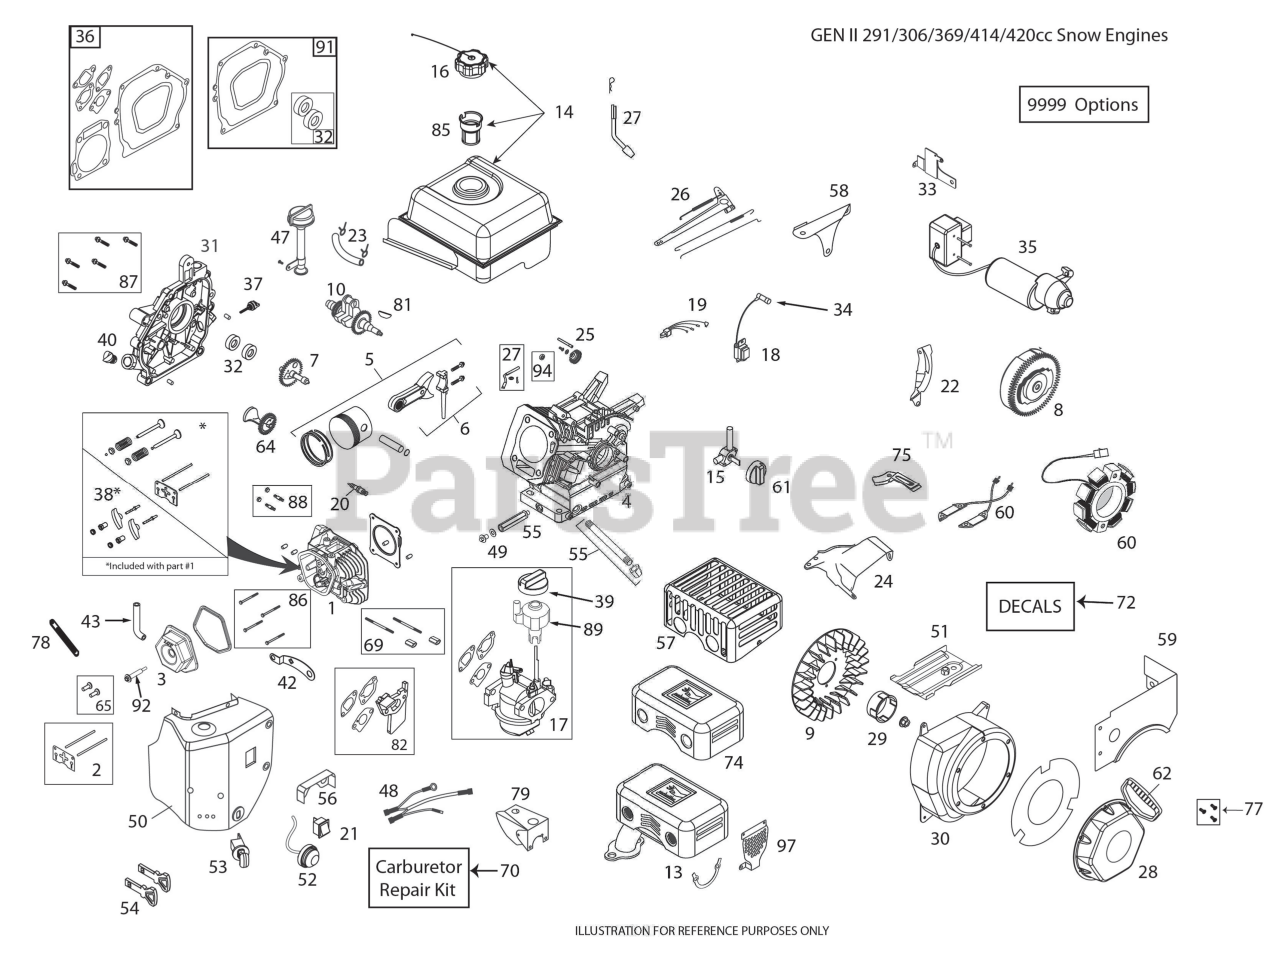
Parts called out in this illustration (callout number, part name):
1	CYLINDER.HEAD.ASSY(SK2911000)
2	PUSH ROD TAPPET KIT
3	VALVE.COVER.LCT.414CC.
4	CYLINDER ASSY SNO.LCT
5	PISTON.AND.ROD.ASSY(SK2911400)
6	CONNECTING ROD ASSY SNO.LCT
7	CAMSHAFT.LCT.291CC
8	FLYWHEEL.EL.ST.SKSNO2401.1
9	FLYWHEEL.FAN
10	CRANKSHAFT
13	MUFFLER ASSY LCT SNO
14	FUEL TANK ASSY - SNOW (291CC)
15	FUEL.PETCOCK.SNOW(SKSN4900)
16	FUEL.TANK.CAP.SNOW(SKSN4301)
17	CARBURETORS
18	COIL.IGN.CDI.SKSN2403.1
20	SPARK.PLUG(SK2911550)
21	ON/OFF.SWITCH.SNOW(SKSN4403)
23	FUEL HOSE KIT
24	TOP.SHIELD.LCT.
25	GOVERNOR.GEAR.ASSY(SK2912900)
26	GOVERNOR.ARM.ASSY.(SKSN2502)
27	GOVERNOR.SHAFT.(SK2913100)
28	STARTER RECOIL.291/306CC.LCT
29	STARTER CUP.LCT.291/306CC
30	BLOWER HOUSING.LCT.291/306CC W
31	CRANKCASE.COVER.ASY(SK2913600)
32	OIL.SEAL.KIT(SK2913900)
33	SWITCHBOX BRACKET ES LCT 291 S
34	SPARK.PLUG.BOOT.SNW,SKSN4691.1
35	STARTER, ELECTRIC, 230V
36	ENGINE.GASKET.KIT(SK2914300)
37	DIPSTK.OIL.BLK.LCTSK4143711.1
38	ROCKER ARM KIT
39	CHOKE.KNOW.SNOW(SKSN4500)
40	NONREMVABLE.OIL.PLUG(SK4143715
42	CDI.BOX.BRKT.SNOW(SKSN4402)
43	BREATHER TUBE LCT 291/369/414
47	HIGHOIL.FILL.ASSY.KIT(SKSN4911
48	WIRE.HARNESS(SKSN4406)
50	HEATER.BOX.ASSY.SNOW(SKSN2100)
51	SHIELD.CYLINDER.SNOW(SK4141010
52	PRIMER.BULB.ASSY(SKSN4304)
53	KEY.SWITCH.ASSY.SNOW(SKSN4401)
54	KEY SET(2 KEYS) SKSN0407.1
55	OIL PIPE DRAIN EXTENDED.LCT SK
56	SHIELD.VAPOR(SKSN4606)
57	MUFFLER GUARD.CE.LCT
58	GOVERNOR.LINK.SHIELD(SKSN2501)
59	FUEL TANK SKIRT.LCT.291/306CC
60	ALTERN.60WATT.SKSN2402.1
61	FUEL KNOB-SNOW
62	HANDLE.RECOIL.DELUXE.LCT
65	TAPPET KIT.LCT.SK2911005.1
69	STUD.CARB.MOUTING.KIT.291CC
70	CARBURETTOR REPAIR KIT 291CC/4
74	MUFFLER SHIELD
75	WIRE GUARD
77	BOLT.KIT.RECOIL.LCT.ALL.ENGINE
79	SHIELD CARBURRETOR COVER 414
82	SPACER.CARBURETOR.291CC.LCT
85	STRAINER.FUEL.TANK.LCT.208CC
86	KIT.BOLT.CYLINDER.HEAD.(4PC)
87	KIT.7-BOLT.CRANKCASE.CVR.291CC
88	STUD.MUFFLER.KIT.LCT
89	KNOB LCT.SKSN5325.1 SPEED
91	GASKET KIT CRANKSHAFT.LCT
92	CENTER VALVE COVER BOLT
9999	HIGH.ALTITUDE.JET.6000FT ANDUP
9999	KIT.BOLT.LCT.SK9990.1
